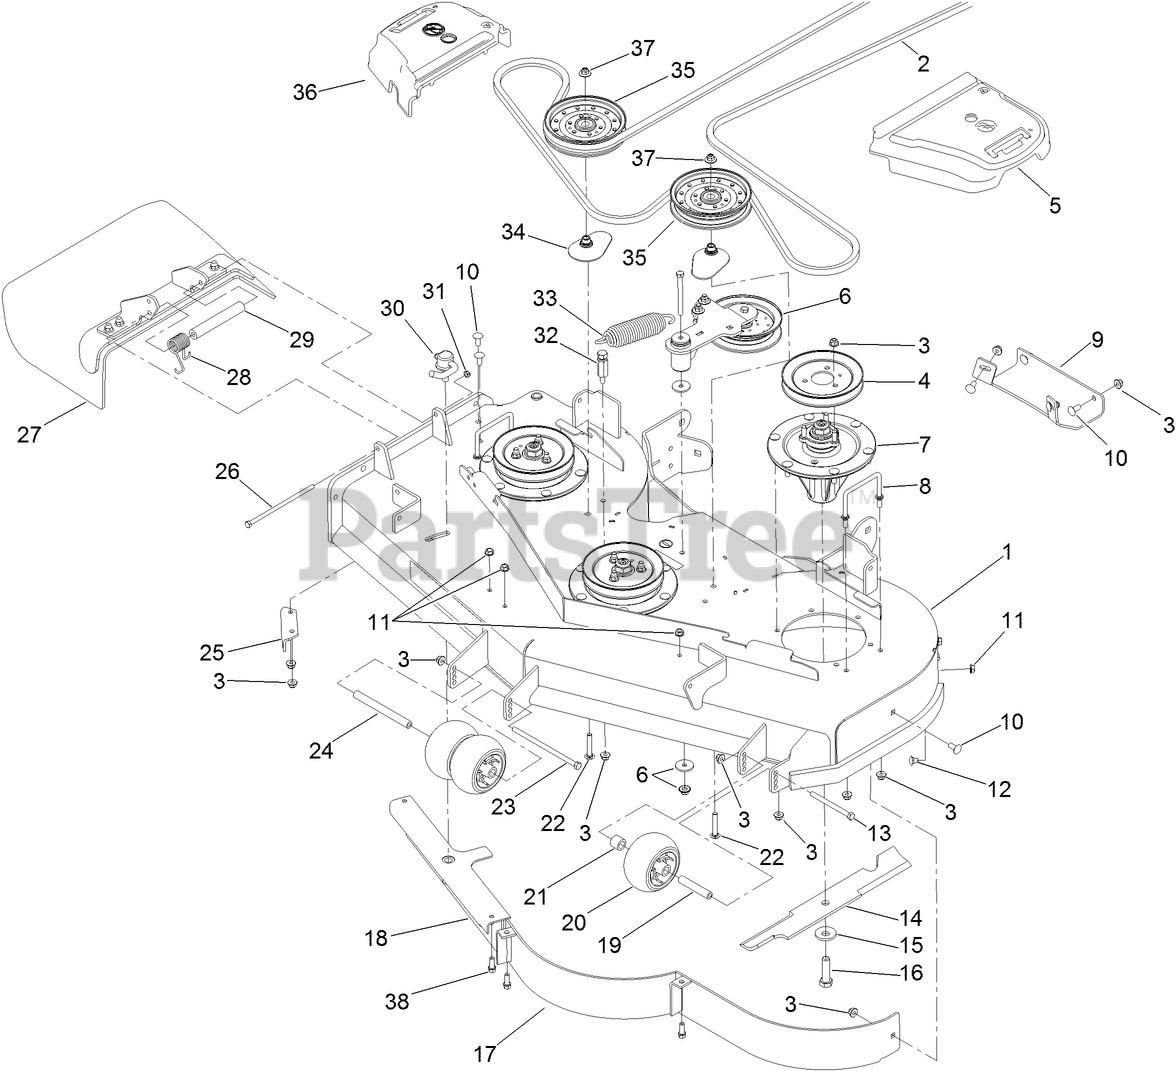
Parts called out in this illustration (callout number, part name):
1	DECK DECAL ASM
2	BELT-V
3	NUT-HF, NI
4	PULLEY
5	COVER-BELT, LH
6	IDLER ARM ASM
7	SPINDLE ASM
8	WIREFORM-COVER
9	PLATE-SKID
10	SCREW-CARR
11	NUT-HHF, WHIZ
12	SCREW-CARR
13	SCREW-HH
14	BLADE-18IN, HI FLOW
15	Washer-Blade Bolt, Heavy
16	SCREW-BLADE
17	BAFFLE ASM
18	BAFFLE
19	TUBE-SPANNER
20	ROLLER-SCALP, ANTI
21	TUBE-SPACER
22	BOLT-CARR, SHORT NECK
23	SCREW-HH
24	SPACER-WHEEL
25	BAFFLE-DISCHARGE
26	SCREW-HH
27	RUBBER DEFLECTOR ASM
28	SPRING-TORSION
29	SPACER
30	LEVER ASM
31	NUT-LOCK, NI
32	ANCHOR-SPRING, TALL
33	EXTENSION-SPRING
34	SPACER-PULLEY
35	PULLEY-IDLER, FLAT
36	COVER-BELT, RH
37	NUT-FLANGE, NI
38	SCREW-HWH
